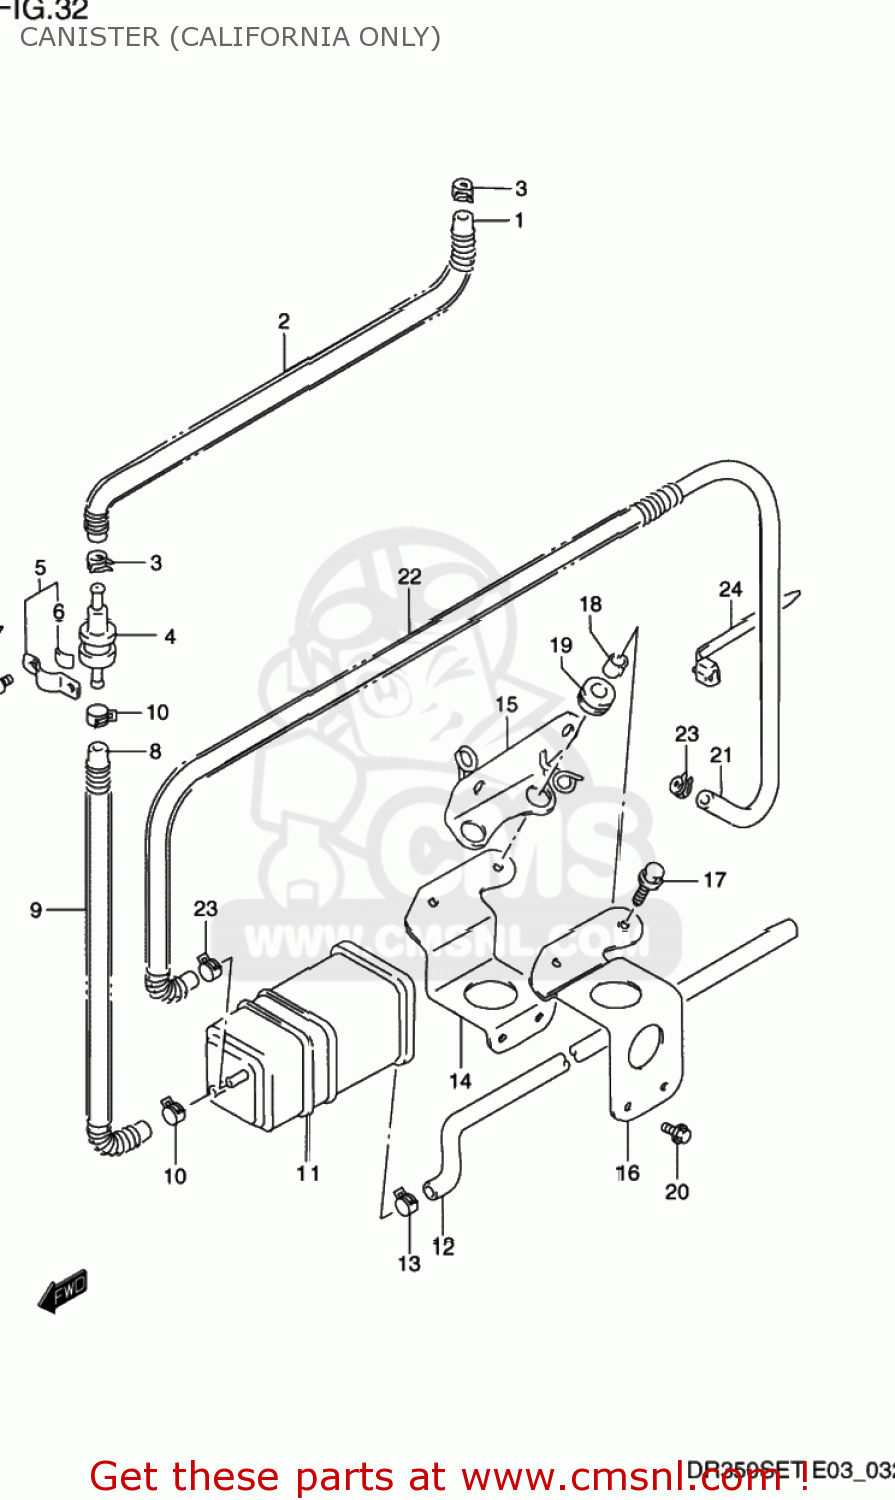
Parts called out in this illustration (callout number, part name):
1	HOSE
2	SPRING
3	CLIP
4	VALVE,FUEL TANK BREATHER
5	PLATE,FUEL TANK BREATHER NO.2
6	CUSHION
7	SCREW
8	HOSE
9	SPRING
10	CLIP
11	CANISTER ASSY,CHARCOAL
12	HOSE,CANISTER PURGE AIR
13	CLIP
14	PLATE COMP,CANISTER,LOWER
15	PLATE COMP,CANISTER
16	PLATE,CANISTER,UPPER
17	BOLT(6X23)
18	SPACER (6,8X10X9.4)
19	CUSHION
20	BOLT
21	HOSE (5.4X11.4X790)
22	SPRING
23	CLIP
24	CLAMP(L:125)
